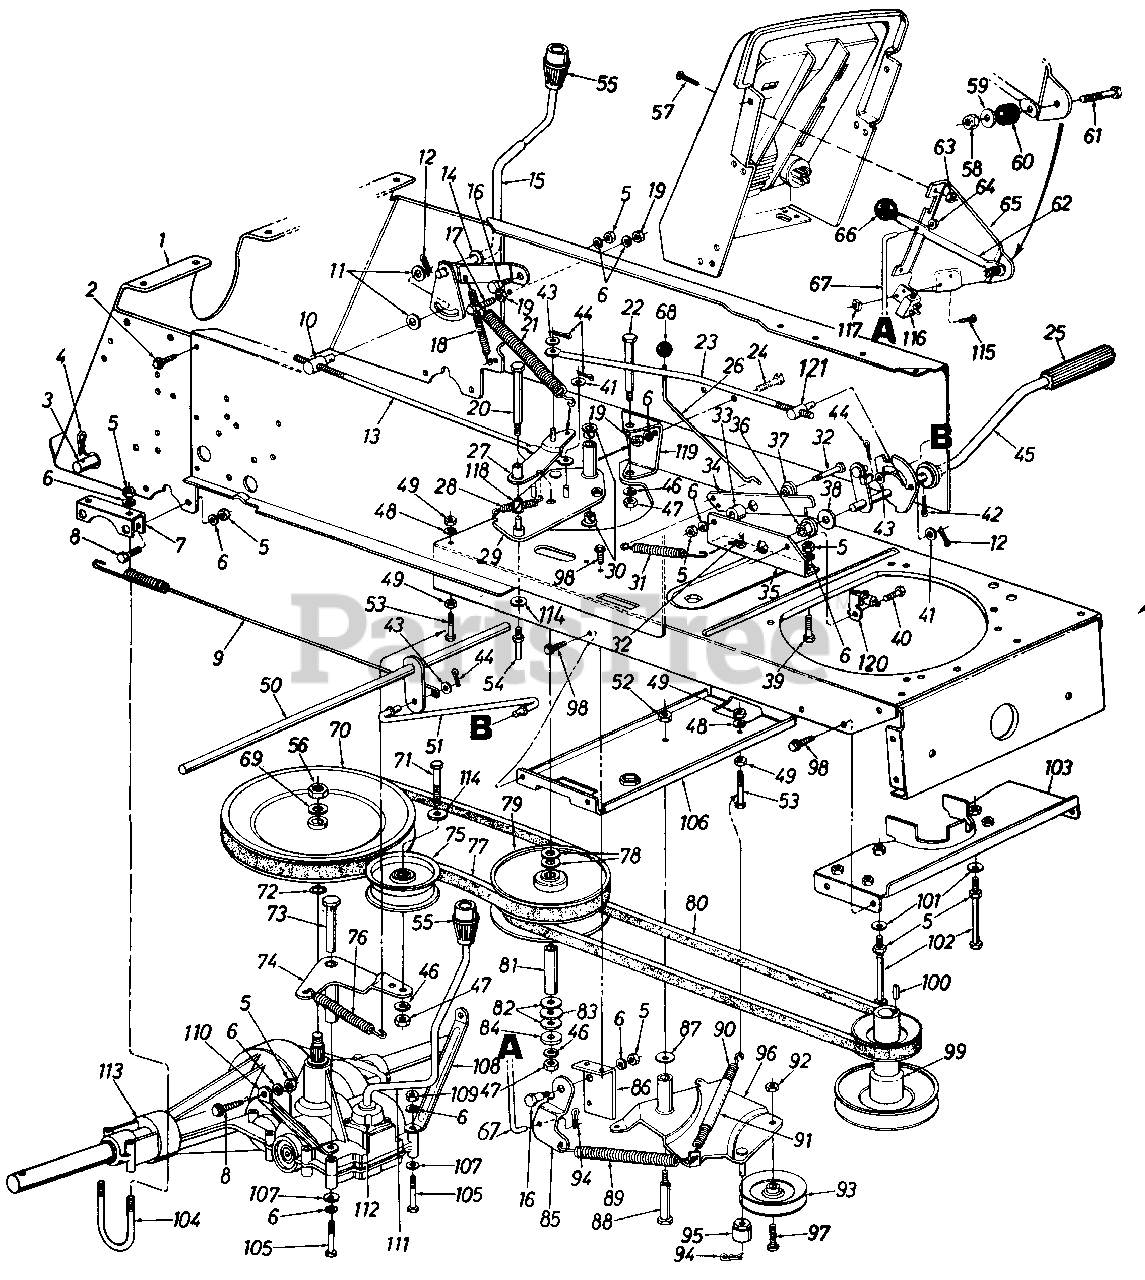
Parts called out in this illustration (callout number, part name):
4	Hitch Pin Clip
5	Hex Nut 5/16-18 Thd.
6	L-Wash. 5/16" l.D.
7	Transaxle Bracket
8	Hex Bolt 5/16-18 x .75" Lg. (Gr. 5)
9	Brake Extension Spring
10	Adjustment Ferrule 3/8-24 Thd.
11	Fl-Wash. .385" I.D. x .67"
12	Internal Cotter Pin
13	Speed Control Link
14	Fl-Wash. .531" I.D. x .94"
15	Speed Selector Lever Ass'y.
16	Shld. Bolt .437" Dia. x .162"
17	Hex Bolt 5/16-24 x 1.25" Lg.
18	Extension Spring 3,9" Lg.
19	Hex Nut 5/16-24 Thd. (Gr. 5)
20	Hex Bolt 3/8-24 x 4.5" Lg.
21	Extension Spring 11" Lg.
22	Shld. Bolt .625" Dia. x 3.5" Lg.
23	Speed Control Link
24	Hex Bolt 5/16-24 x ,75" Lg.
25	Foot Pad
26	Parking Brake Link
27	Var. Speed Torque Brkt. Ass'y.
28	Extension Spring 2.59" Lg.
29	Pulley Brkt. Sub Ass'y.
30	Flanged Brg. .625" I.D.
31	Extension Spring 2.51" Lg.
32	Hex Bolt 5/16-18 x 1.25" Lg.
33	Spacer .34" I.D. x .88"
36	Hex Flange Brg. .634" I.D.
37	Shld. Spacer ,5" Dia.
38	Fl-Wash. .64" I.D. x 1.24"
39	Hex Bolt 5/16-18 x .75" Lg.
40	Hex Tap Scr. #10-32 x 5/8" Lg.
41	Fl-Wash. .406" I.D. x .75" O.D.
42	Cotter Pin 1/8" Dia.
43	Fl-Wash. .34" I.D. x .68" O.D.
44	Cotter Pin 3/32" Dia.
45	Foot Pedal Brkt. Ass'y.
46	L-Wash. 3/8" l.D.
47	Hex Nut 3/8-24 Thd.
48	L-Wash. 1/4" l.D.
49	Hex Nut 1/4-20 Thd.
50	Brake Link Bracket
51	Front Brake Rod Link
52	Hex Cent. L-Nut 3/8-16 Thd.
53	Hex Bolt 1/4-20 x 2.0" Lg.
54	Belt Guard Pin
56	Hex Jam Nut 9/16-18 Thd.
57	Truss Mach. Scr. 1/4-20 x .5" Lg.
58	Hex Ins. L-Nut 1/4-20 Thd.
59	Fl-Wash. .281' I.D. x .73" O.D.
60	Rubber Washer .33" I.D.
61	Hex Bolt 1/4-20 x 1.25" Lg.
62	Blade Clutch Lever
63	Hex Sems Nut 1/4-20 Thd.
64	Push Nut l/4" O.D. Rod
65	Deck Clutch Control Brkt.
66	Knob-Blade Clutch
67	Deck Control Rod
68	Ball Knob Brake
69	Bell-Wash. 9/16" l.D. x 1.25"
70	V-Pulley 9l/4" O.D.
71	Hex Bolt 3/8-24 x 1.75" Lg.
73	Shld. Bolt 5/16-24 Thd.
74	Idler Brkt. Ass'y.
75	Flat Idler 3.5" O.D.
76	Extension Spring 6.12" Lg.
77	V-Belt
78	Teflon Washer 1.20" O.D.
79	Variable Speed Pulley 6" Dia.
80	V-Belt
81	Pivot Bushing
82	Fl-Wash. 56" l.D. x 1.0" O.D.
83	Thrust Brg. .56" I.D. x 1.25"
84	Retainer Cup
85	Deck Control Pivot Brkt.
86	Parking Brake Mtg. Brkt.
87	Bell-Wash. .38" I.D. x .88" O.D.
88	Shld. Bolt 498" Dia. x 2.05"
89	Extension Spring 6.12" Lg.
90	Extension Spring 6 37" Lg.
91	Convoluted Conduit 4" Lg.
92	Hex Cent. L-Nut 3/8-24 Thd.
93	V-Belt Idler
94	Internal Cotter Pin
95	Spacer
96	Idler Brkt. Deck Ass'y.
97	Hex Bolt 3/8-24 x 1.5" Lg.
98	Hex TT-Tap Scr. 1/4-20 x 5n
99	Engine Pulley
100	Sq. Key 1/4 x 1.5" Lg.
101	Bell-Wash. .345" I.D. x .88n
102	Hex Bolt 5/16-18 x 5.25" Lg.
103	Belt Keeper Brkt. Ass'y.
105	Hex Bolt 5/16-24 x 2.25" Lg.
106	Deck Idler Support Brkt.
107	Fl-Wash. 344" l.D. x .62" O.D.
108	Front Trans. Support Brkt.-L.H.
109	Hex Nut 5/16-24 Thd.
110	Front Trans. Support Brkt.-R.H.
111	Shift Lever Ass'y. Complete
112	Socket Hd. Cap Scr. #10 x 24
113	2-Speed Transmission Comp.
114	Fl-Wash. 3/8" I.D. x 1.0" O.D.
115	Truss Mach. Scr. #10-24 x .5"
116	Safety Switch
117	Hex Nut #10-24 Thd.
118	Nyliner Flanged Brg.
119	Variable Speed Support Br.
120	Safety Switch
121	Adjustment Ferrule 3/8-24 Thd.
